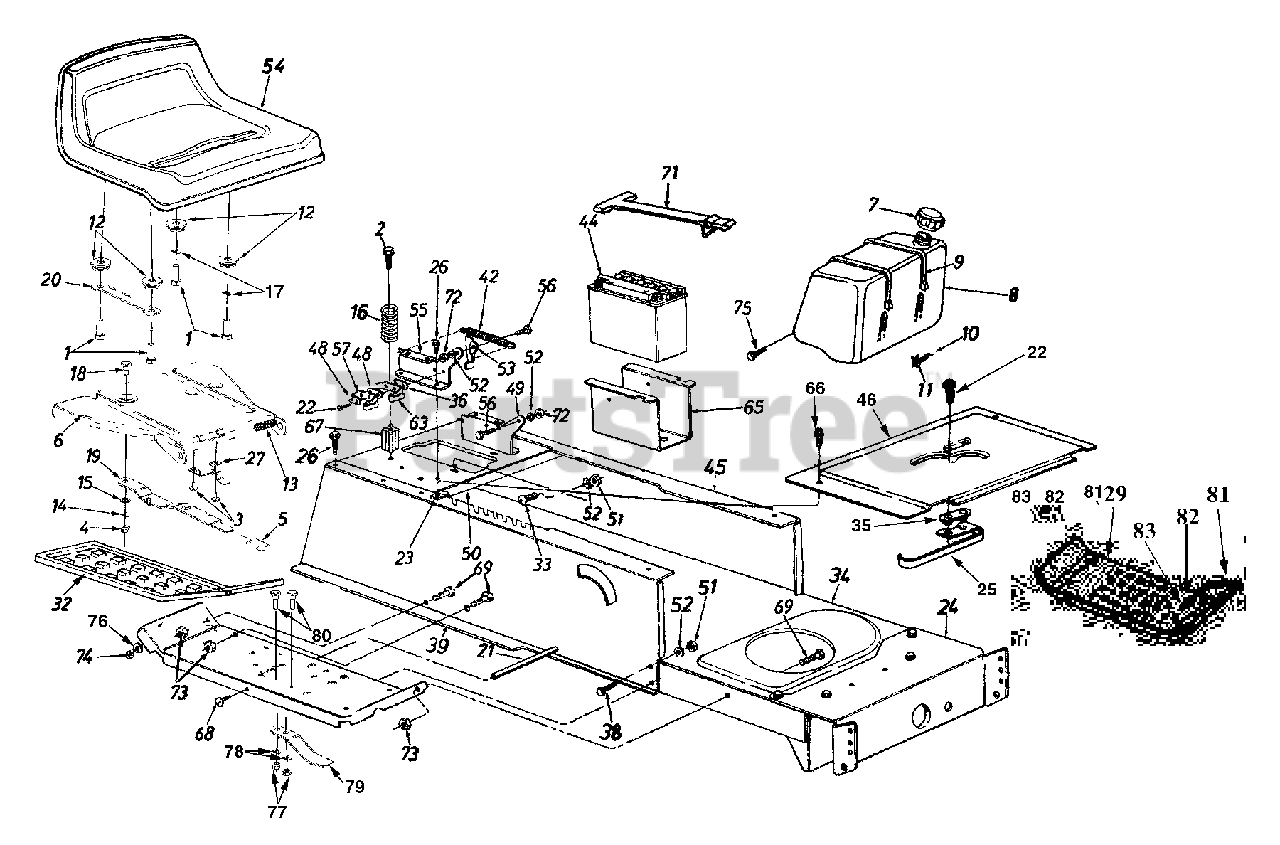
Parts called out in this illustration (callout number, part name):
1	Shoulder Screw 3/8-16 x .5
2	Hex Washer Tap Scr. 5/16-18 x 3.25" Lg.
3	Hx Scr. B-Tap Wash. #10-16:.38 Lg.
4	Lock Nut 1/4-20
8	Fuel Tank
9	Tie Strap
10	Fuel Line
13	Compression Spring
14	Wash. Spring .265 x .562 x .025
15	Fl. Wash. .344 ID x .62 OD x .03
16	Compression Spring
17	Flat Washer .535 x .93 x .090
18	Shldr. Scr. .340 x .285 - 1/4-20
20	Seat Selector
21	Running Board Rod
22	Hex AB-Tap Scr. #8 x .50"
23	Speed Nut #10Z
25	Reverse Safety Switch
26	Hex Washer AB-Tap Scr. 5/16 x .75" Lg.
33	Truss Mach. Scr. 5/16-18 x .75" Lg.
35	Insalatop Nut Plate
36	Insulator Boss Plate
38	Hex Bolt 5/16-18 x .75" Lg.
44	12-V Battery
48	Insulator Plate
52	L-Wash. 5/16" I.D.
53	Seat Lift Brkt.
54	Seat
56	Shld. Bolt .437" Dia. x .268"
57	Spring Switch
63	Safety Switch (Seat)
66	Truss Mach. B-Tap Scr. #10 x .5" Lg.
67	Spring Spacer
68	Pan Hd. Scr. 5/16-18 x .75" Lg.
69	Hex Bolt 5/16-18 x .75" Lg.
71	Battery Retainer Strap
72	Hex Nut 5/16-18 Thd. (Gr. 5)
73	Hex Sems Nut 5/16-18 Thd.
74	Hex Sems Nut 1/4-20 Thd.
75	Hex Screw 12-24 x .62
76	Bell Wash. .265 x .75 x .062
77	Hex Nut 1/4-20 Gr. 5
78	L-Wash.
79	Blade Brake Asm.
80	Hex Carriage Screw 1/4-20 x .75"Lg.
82	Spring Wash.
83	Hex Nut 3/8-16 Gr. 5
